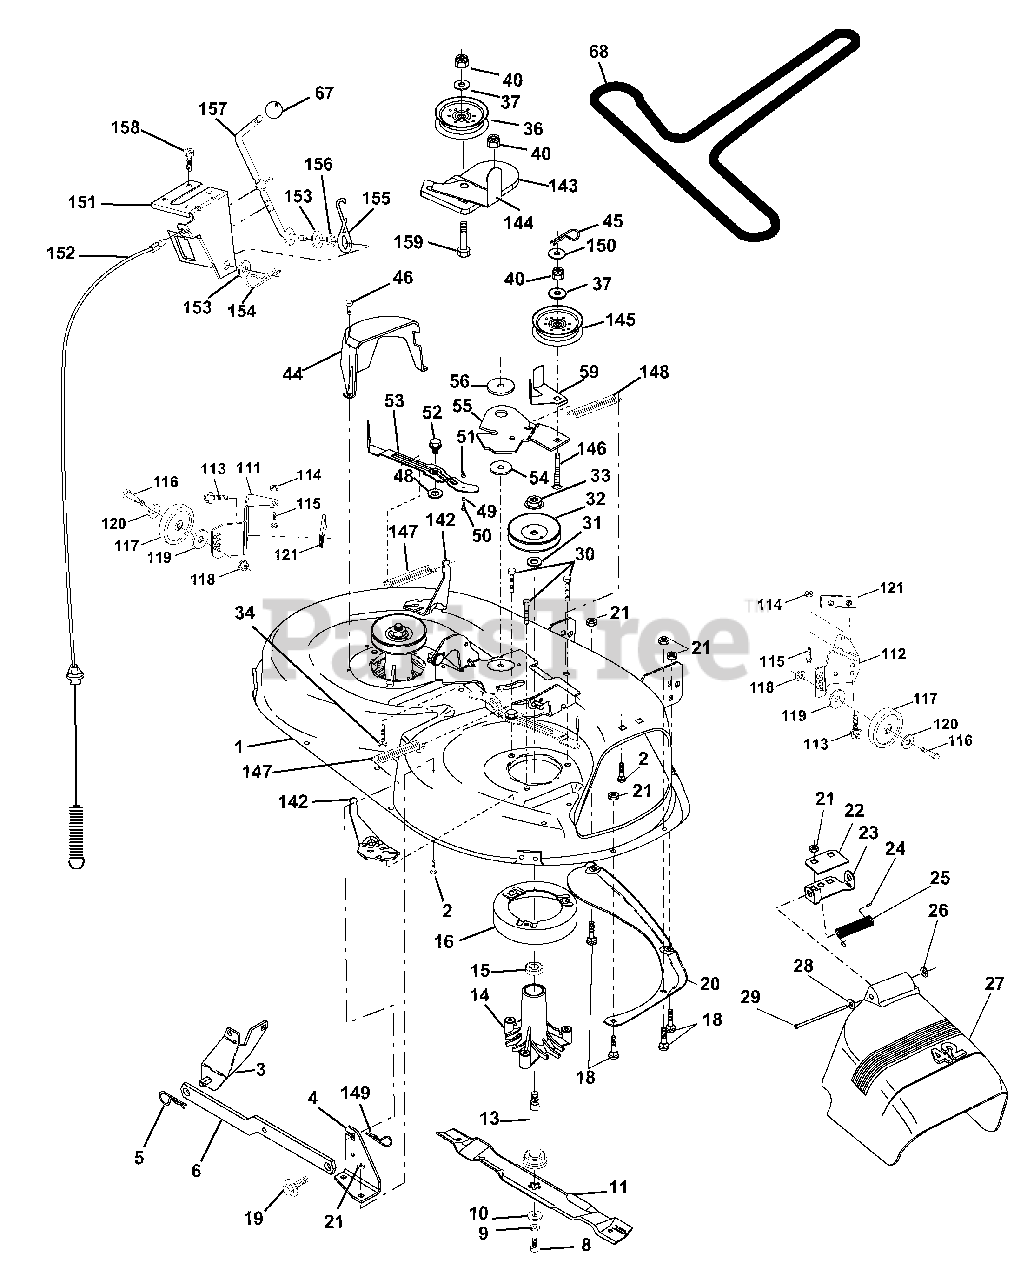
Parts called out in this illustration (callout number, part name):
1	Mower Deck Assembly, 42"
2	Bolt
3	Bracket Asm Fr. Sway Bar 3/42
4	Bracket Asm Deck 42" Sway Bar
5	Retainer Spring
6	Arm, Suspension, Rear
8	Bolt 3/8-24 x 25 Grade 8 patched
9	Washer, Lock
10	Washer,Hardened
11	Blade
13	Shaft Assembly, Mandrel, Vented
14	Housing, Mandrel, Vented
15	Bearing, Ball, Mandrel
16	Stripper, Vented Mower Deck
18	Bolt, Carriage 5/16-18 x 5/8
19	Bolt, Shoulder
20	Baffle, Vortex
21	Nut
22	Stiffener Bracket
23	Bracket, Deflector Mower 42"
24	Cap, Sleeve 80 x 112 Blk Mower
25	Spring, Torsion, Deflector 2 52
26	Nut, Push Phos & Oil
27	Shield, Deflector 42" Blk
28	Washer 11/32 x 5/8 x 16 Gauge
29	Rod, Hinge 42" 6 75 W/G
30	Screw Thdrol Washer Head
31	Washer, Spacer Mower Vented
32	Pulley, Mandrel
33	Nut, Toplock 9/16
34	Bolt
36	Pulley, Idler, Flat
37	Washer 13/32 x 13/16 x 16 Gauge
40	Nut
44	Guard, Mandrel, LH
45	Retainer
46	Screw, Thdrol 1/4-20 x 5/8 T
48	Washer,Hardened
49	Roller Assembly, Cam Follower
50	Bolt, Shoulder #10-24 Grade 5
51	Locknut
52	Bolt, Shoulder 5/16-18 UNC
53	Arm Assembly, Pad, Brake
54	Washer,Hardened
55	Arm, Idler
56	Spacer, Retainer
59	Guard TUV Idler
67	Knob
68	V-Belt, 42" Mower
111	Bracket, Gauge, Wheel LH
112	Bracket, Gauge, Wheel RH
113	Screw 5/16 - 18
114	Nut, Keps 5/16 - 18 UNC
115	Bolt, Carriage 5/16-18 x 1/2
116	Bolt, Shoulder
117	Wheel, Gauge
118	Nut Centerlock 3/8-16
119	Washer 3/8 x 7/8 x 14 Ga.
120	Washer 17/32 x 15/16 x 12 Ga.
121	Bracket, Extruded
142	Arm Spring Brake Mower
143	Bracket Arm Idler 42"
144	Keeper Belt 42" Clutch Cable
145	Pulley Idler Flat
146	Bolt Carriage Idler
147	Spring Extension
148	Spring Return Idler
149	Retainer Spring Yellow
150	Washer 9/32 x 3/4 x 16 Ga.
151	Bracket Clutch Cable
152	Clutch Cable 42"
153	Washer Flat 3/8" Type B
154	Spring Retainer
155	Spring Retention LVR CLTCH CAB
156	Spacer Clutch Cable
157	Rod Clutch Cable 3/8"
158	Screw Hex Thd Cut 1/4-20 x 5/8
159	Bolt Rdhd Sqn 3/8-16 UNC x 1-3/4
